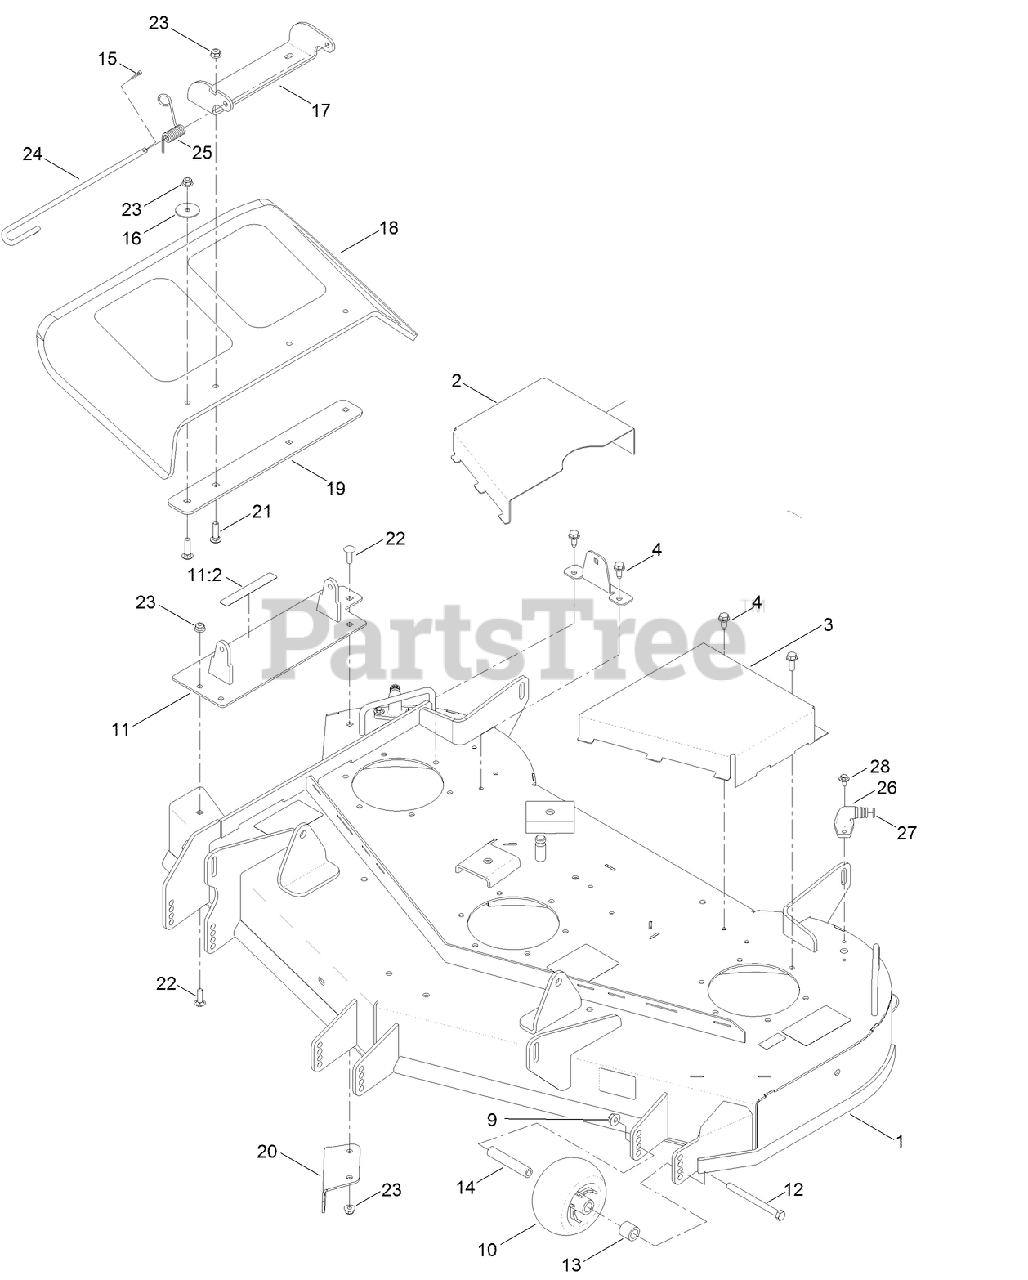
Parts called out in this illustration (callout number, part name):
1	48 INCH DECK ASM
2	COVER-BELT
3	COVER-BELT
4	SCREW-HWHTF
9	NUT-HF, NI
10	ROLLER-SCALP, ANTI
11	PIVOT-DEFLECTOR
11:2	DECAL-DANGER
12	SCREW-HH
13	SPACER-AXLE, REAR
14	TUBE-SPANNER
15	PIN-COTTER
16	WASHER-FLAT
17	BRACKET-DEFLECTOR, UPPER
18	DEFLECTOR
19	PLATE-DEFLECTOR
20	BAFFLE-CUTOFF
21	SCREW-CARR
22	SCREW-CARR
23	NUT-HF, NI
24	PIN-CHUTE
25	SPRING-TORSION
27	O-RING
28	SCREW-HHFTF
